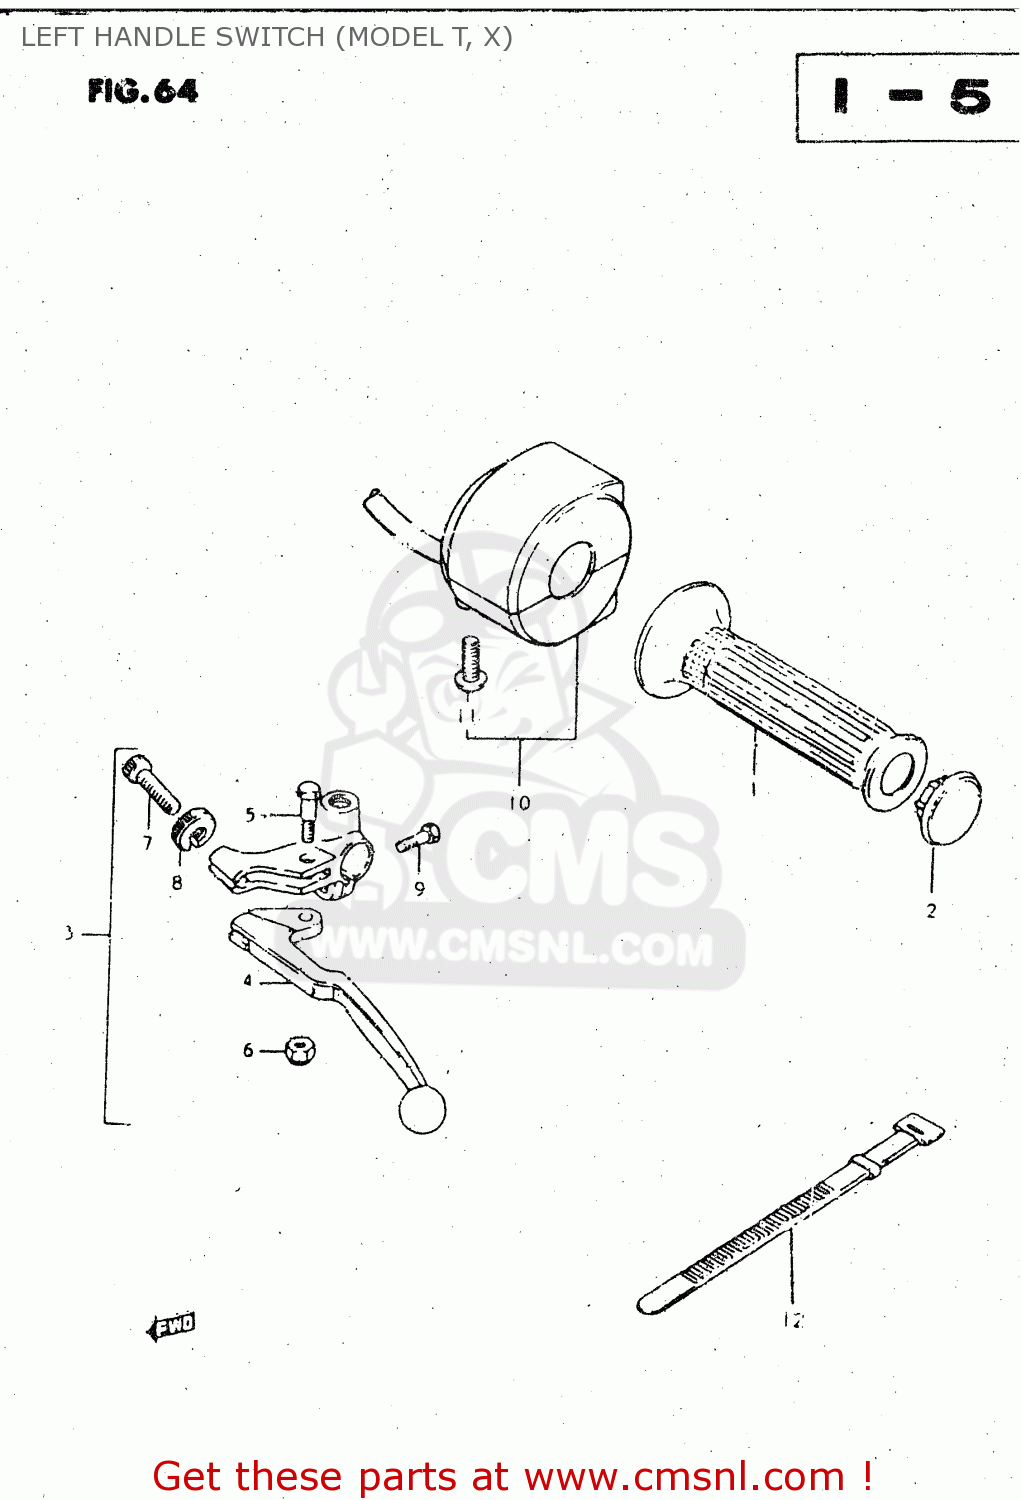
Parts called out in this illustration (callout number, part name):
1	GRIP,LEFT
2	CAP,GRIP END
3	LEVER ASSEMBLY
4	LEVER,CLUTCH
5	BOLT,LEVER
6	NUT 6MM
7	ADJUSTER,CABLE
8	NUT,CABLE ADJUSTER
9	BOLT
10	SWITCH ASSY, HANDLE LH
11	SCREW
12	CLAMP(L:120)
